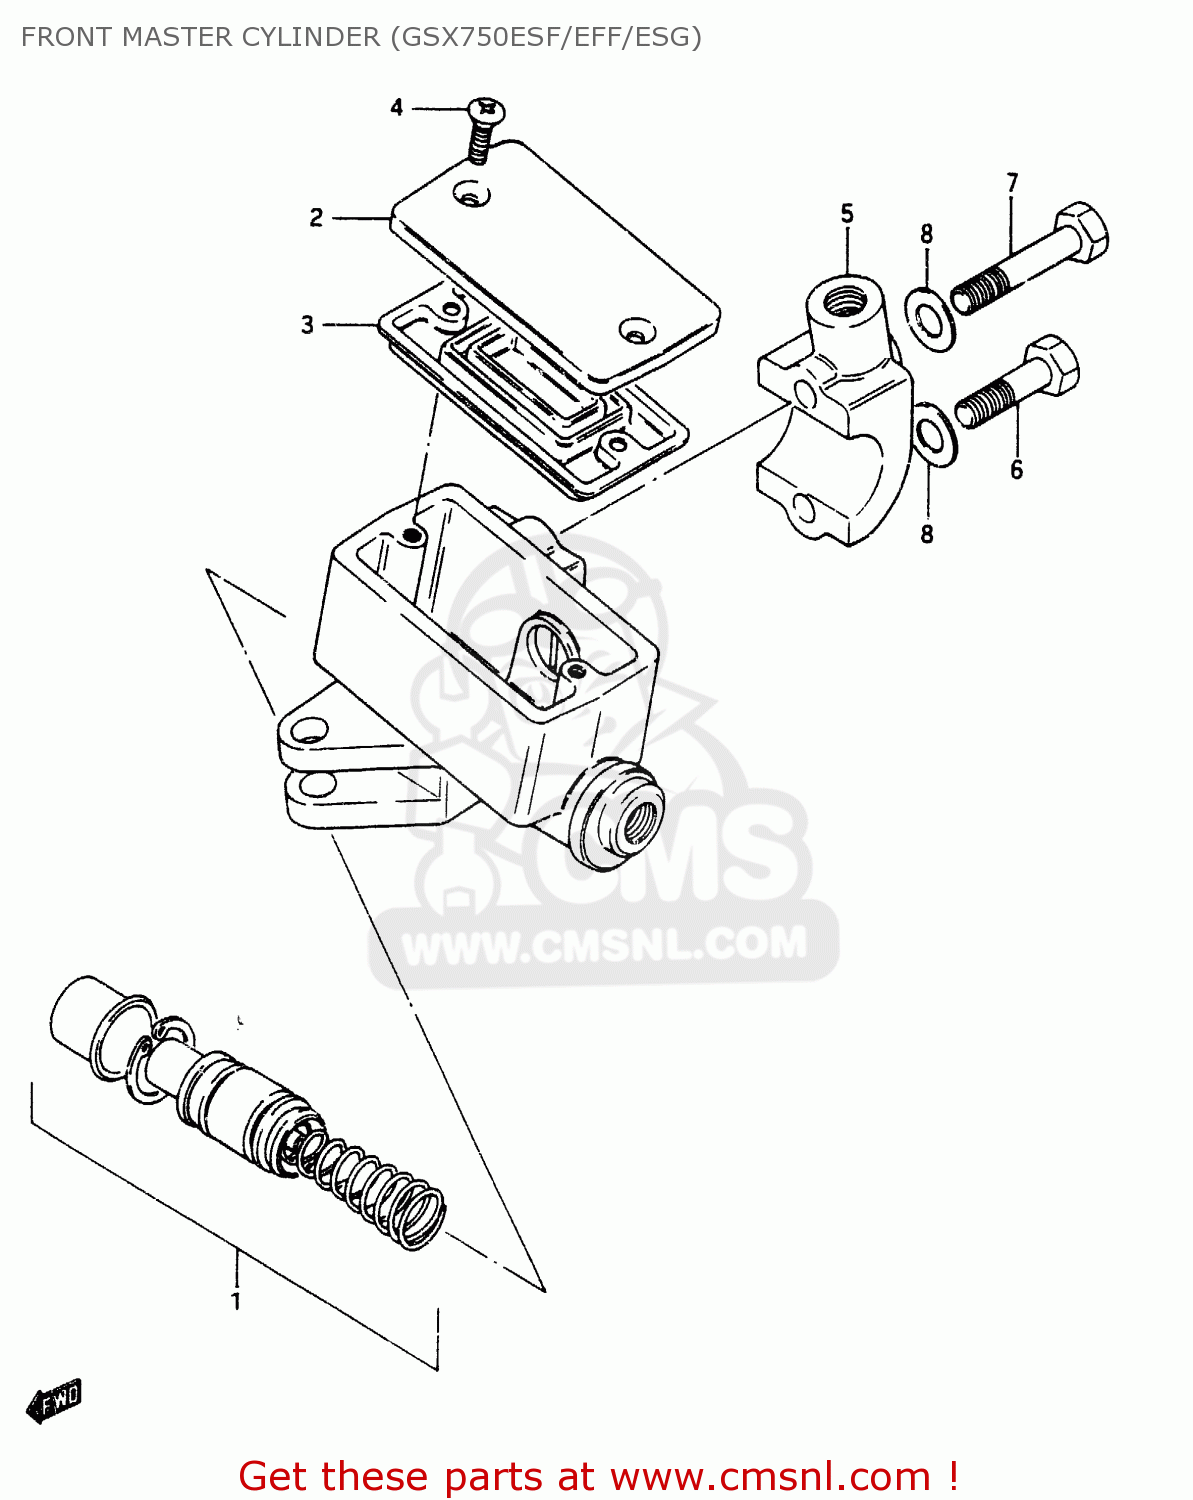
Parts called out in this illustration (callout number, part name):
1	PISTON & CUP SET
2	CAP
3	4
4	SCREW
5	HOLDER
6	BOLT
7	BOLT
8	WASHER
